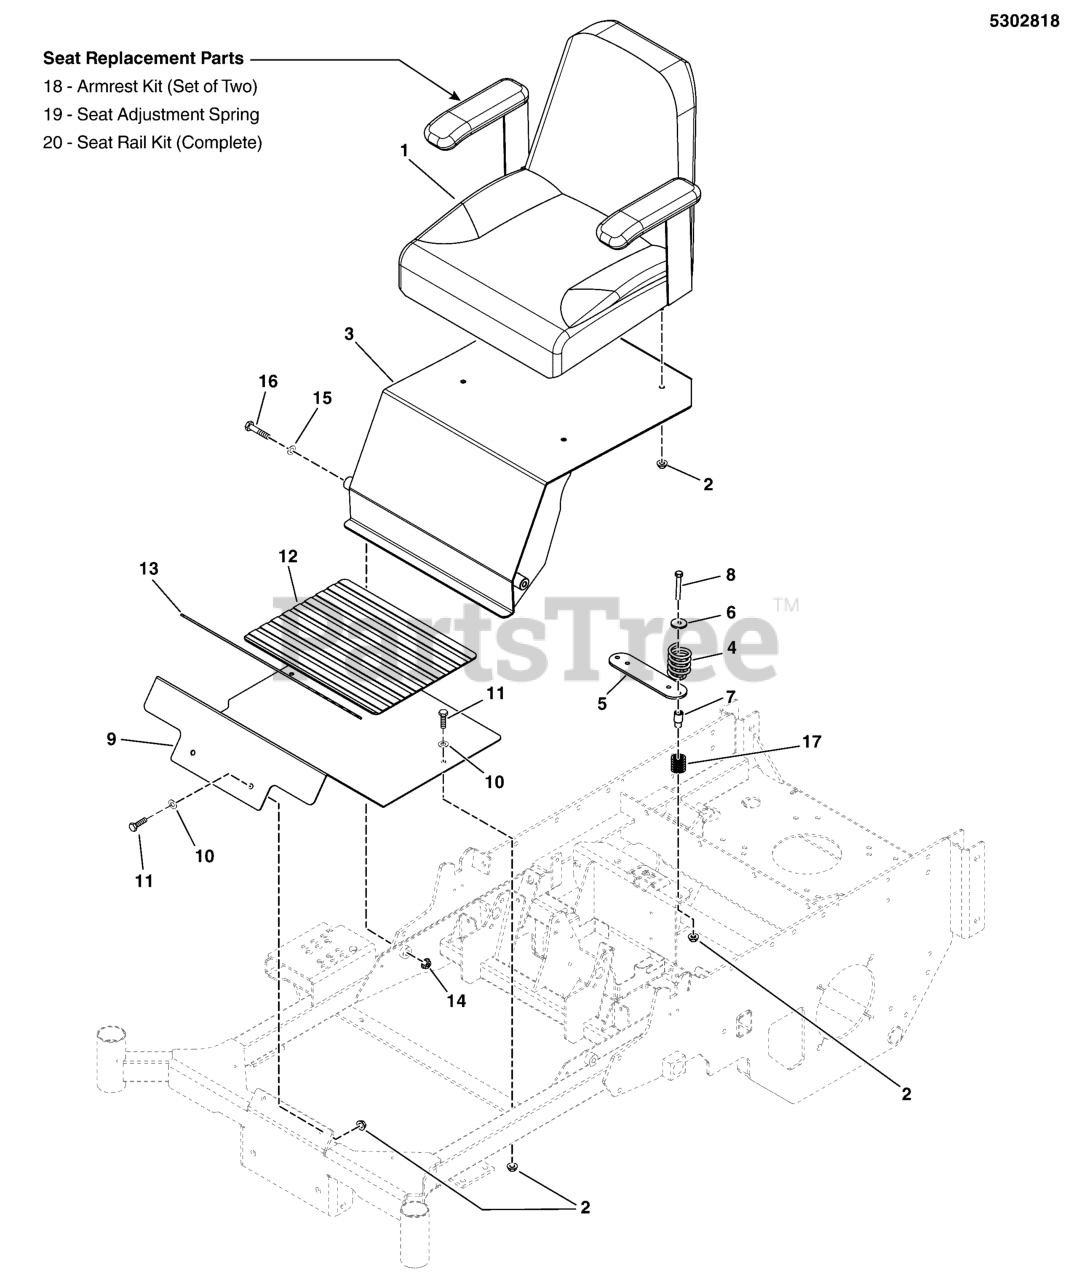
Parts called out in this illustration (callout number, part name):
1	SEAT, XB-180, NO LOGO, BLACK
2	NUT, 5/16-18 HEX NYLOCK FLANGE
3	WELD, SEAT PLATE
4	SPRING, SEAT SUPPORT
5	PLATE, SEAT SWITCH - RED
6	WASHER, .34 X 1.25 X 10 GA
7	SPACER, .33 X .66 X 1.31 SHLDR, CZ
8	BOLT, 5/16-18 X 2-1/4 GD5 YZ
9	PLATE, FLOOR PAN - RED
10	WASHER, 5/16" SAE
11	BOLT, 5/16-18 X 1 GD5 YZ
12	SAFETY WALK, 11.50 X 15.00
13	SAFETY WALK, 8.00 X 15.00
14	NUT, 3/8-16 HEX NYLOCK FLANGE
15	WASHER, 3/8 SAE
16	BOLT, 3/8-16 X 2-3/4" GD5 CZ
17	SPRING COMP .76IDX1.5LGX.105WIRE BLACK
18	ARM REST KIT (SET OF TWO) (SV)
19	SPRING, EXTENSION, SEAT ADJUSTMENT (BLK OR SLVR)
20	KIT, SEAT RAIL (COMPLETE) (SV)
